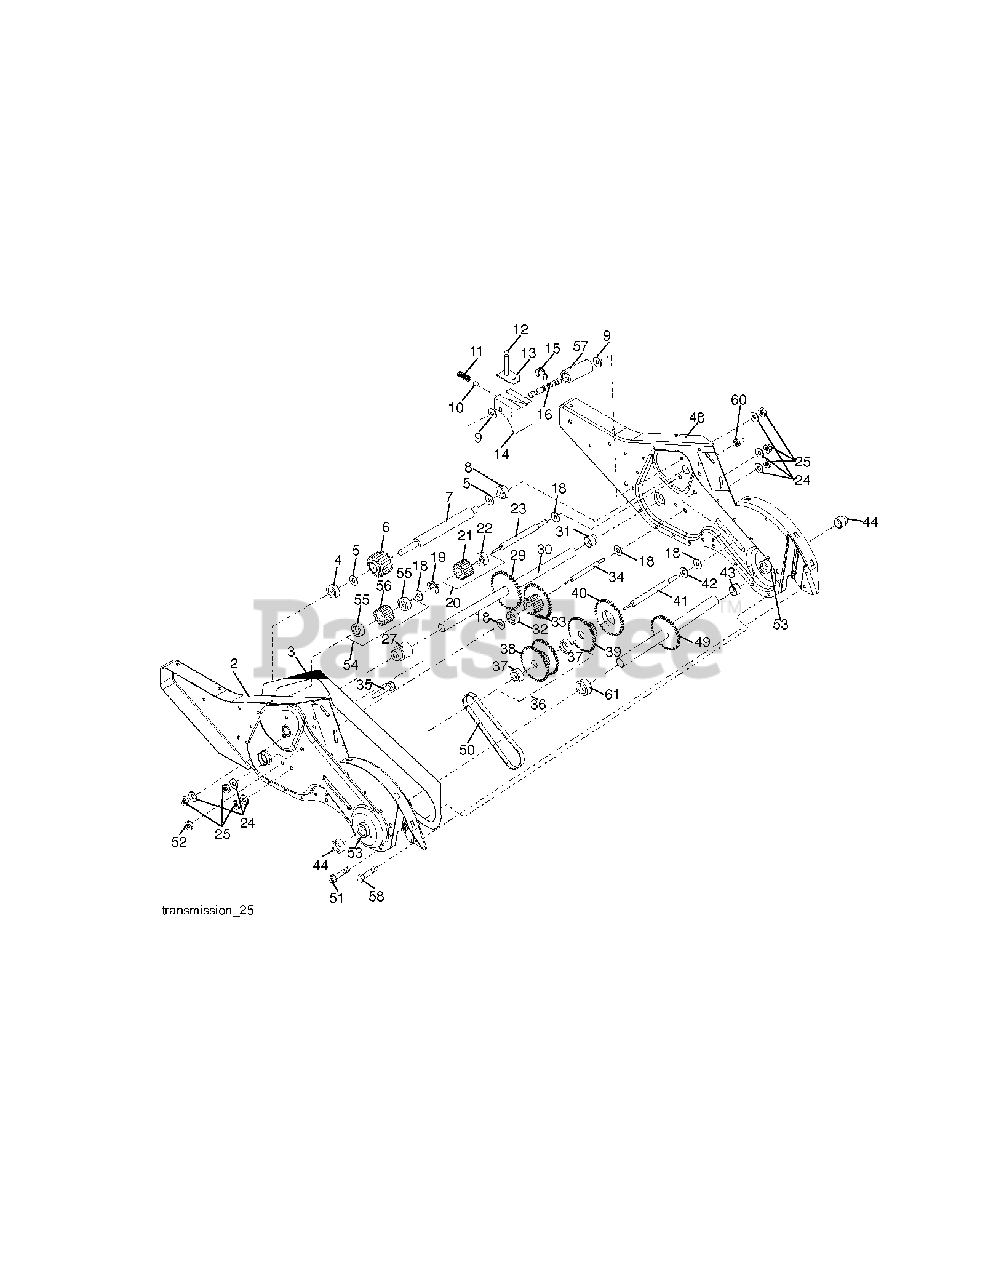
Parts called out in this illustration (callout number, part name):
2	GEARCASE.ASM.DRT.LH.
3	GASKET.GEARCASE.CRT/DRT.TILLER
4	NEEDLE BRNG LT
5	THRUST WASHER
6	GEAR.PINION.INPUT.DRT
7	SHAFT.INPUT.D.9TEETH
9	WASHER, SEAL (2 2)
10	BALL, STEEL
11	SPRING-SHIFT CRT
13	BRACKET ASM.SHIFT.CRT
14	SHIFT FORK TI
16	SHAFT.SHIFT.DRT
20	GEAR ASSY CRT
21	GEAR-REV IDLR CRT
22	NEEDLE BEARING TI
23	SHAFT.IDLER.REVERSE.CRT
24	LOCKWASHER
25	NUT.ASF.HEX.7/16
27	BEARING.GROUND.DRIVE
30	GROUND SHAFT ASS'Y
31	BEARING, SHAFT RH CRT
33	SPRCKT 8 GEAR CRT
34	SHAFT.SECONDARY.REDUCTION.CRT
35	SCRW WHIZ LOK CRT
36	GEAR & SPROCKET.ASM.WBEARIN
37	BEARING.NEEDLE.CRT
38	ASM.GEAR & SPROCKET
39	GEAR.CLUSTER.DRT.TILLER
41	SHAFT.REDUCTION.FIRST.DRT
42	BRNG RACE T
44	SEAL ASM, OIL
48	GEARCASE.ASM.DRT.RH.
49	SHAFT.ASM.TINE
50	CHAIN.TILLER
51	SCREW
53	BEARING KIT
54	GEAR.ASM.DRT.TILLER
55	BEARING.NEEDLE
56	GEAR.DRT.IDLER
57	SPACER.SPLIT
58	BOLT SHOULDER 1/4-20 UNC X.875
60	FITTING.GREASE.TAPERED
61	SPACER.1.015X1.50X.650
